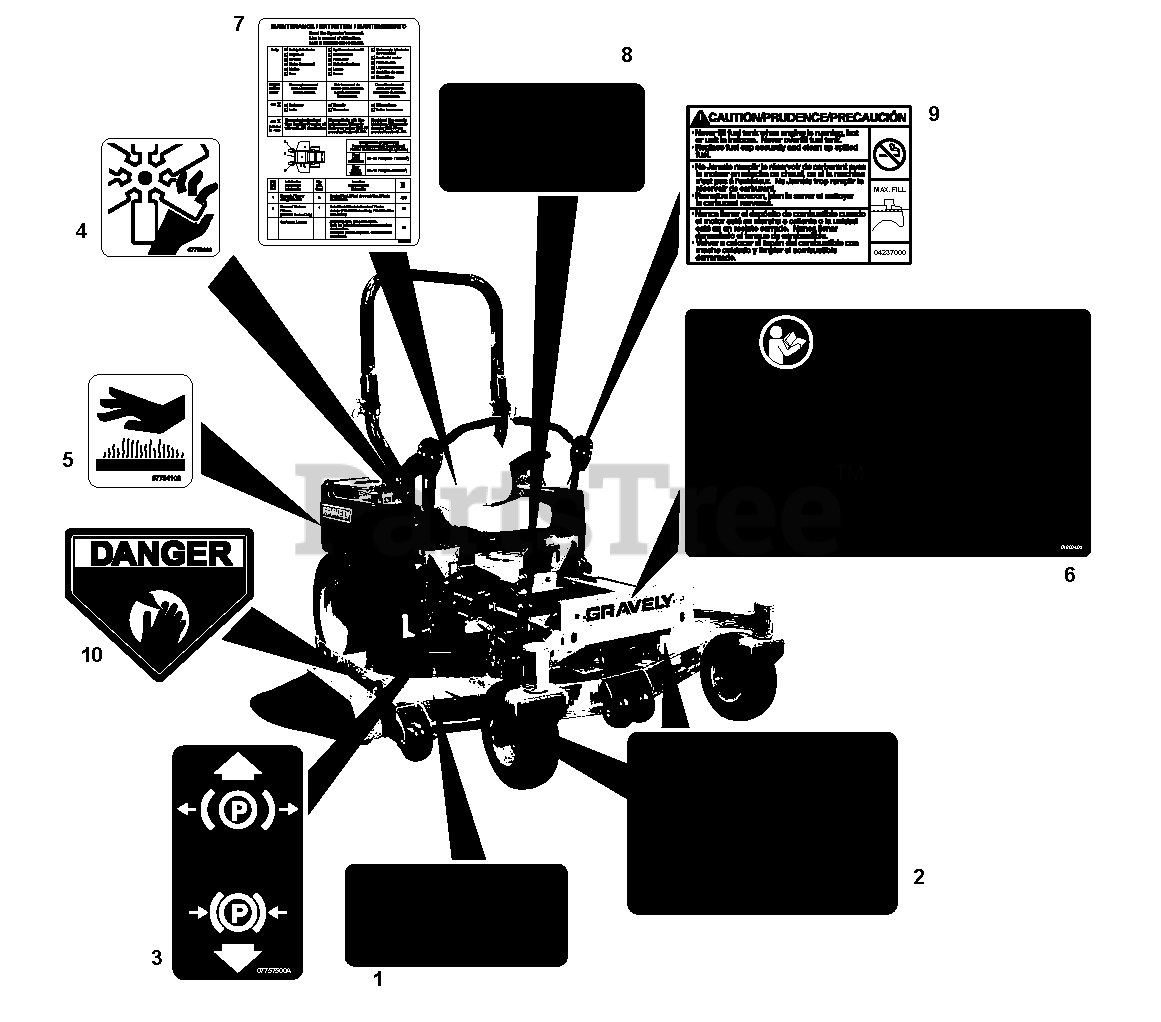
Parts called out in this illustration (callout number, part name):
1	Decal, Safety Deck Guarding
2	Decal, Safety Mower Deck
3	Decal, Parking Brake Lever
4	Decal, Danger Fan
5	Decal, Hot Surface
6	Decal, Main Safety Commercial
7	Decal, Maintenance Instructions
8	Decal, Safety Guarding
9	Decal, Fuel Warning
10	Decal, Danger
